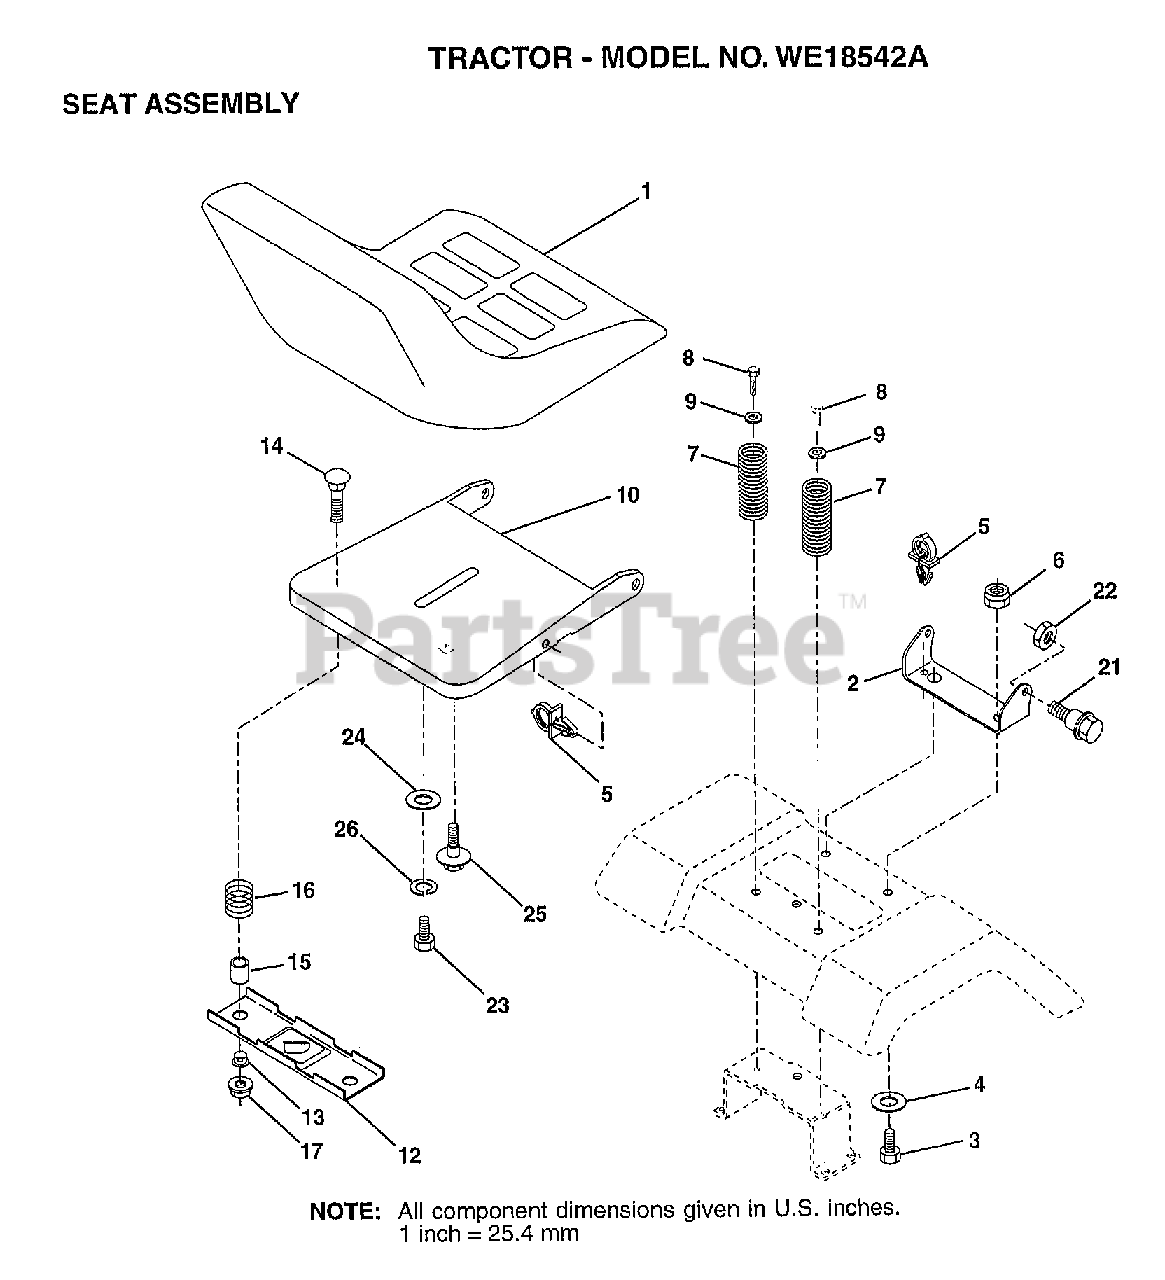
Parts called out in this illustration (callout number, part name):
2	BRACKET PVT SEAT
3	BOLT
4	WASHER PM
5	CLIP.PUSH-IN.HING
6	NUT
7	SPRING COMPRESSIO
8	SCREW GTV
9	WASHER
10	PAN-SEAT
12	BRKT SWITCH
13	BUSHING
15	SPLIT SPACER
16	SPRING
21	"BOLT,SHOULDER"
22	NUT
23	BOLT
24	WASHER
25	"BOLT,SHOULDER"
26	LOCKWASHER
